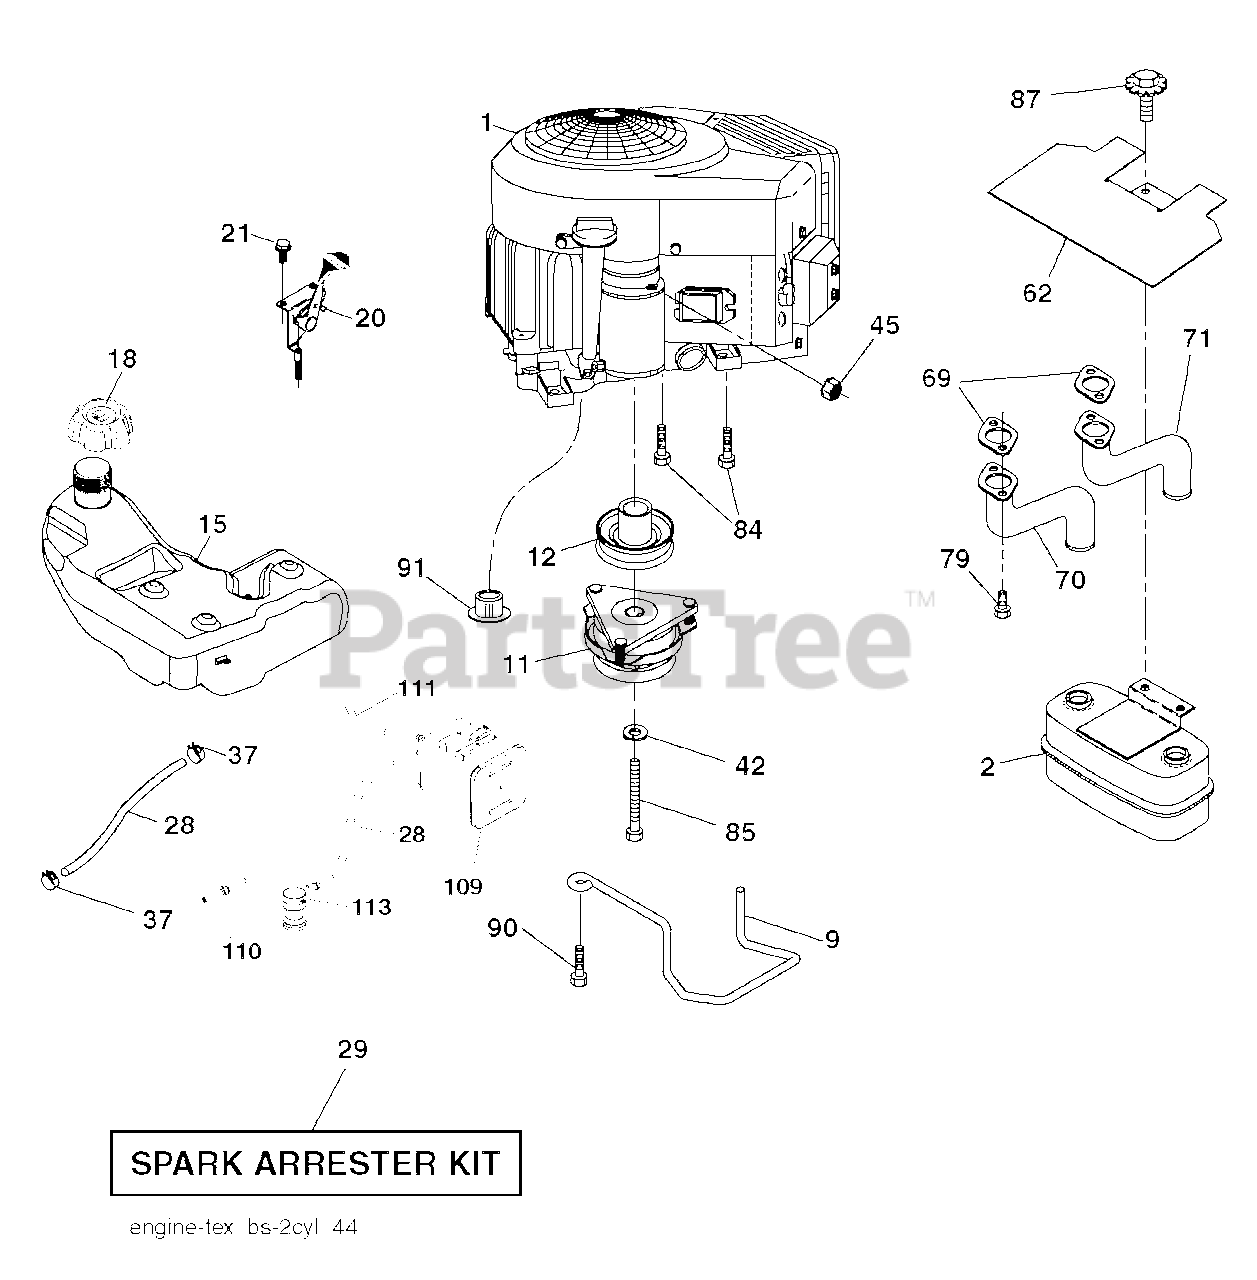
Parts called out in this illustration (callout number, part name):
2	MUFFLER.TWIN.CYL.LOW.TONE
9	KEEPER.BELT.ENGINE.4.2
11	CLUTCH.ELECTRIC.LT.48"*
12	PULLEY.ENGINE.TUFFTORQ
15	TANK.ASM.FUEL.3GA.CARB
18	CAP.ASM.FL.RITCH.3"E10.SYM.498
20	CONTROL.TH/CK.COBRA.B&S.TWN.
21	SCREW.#10 X 0.750.BOS
28	LINE.FUEL.64"REAR.EMIS
29	KIT.SPARK ARRESTOR 794945 B&S
37	HOSE CLAMP
42	LOCKWASHER
45	NUT
62	SHIELD.HEAT.MUFFLER
69	GASKET.MUFFLER
70	RP.EXHAUST.TUBE.LH.BS/TWIN
71	EXHAUST.TUBE.RH.BS/TWIN
79	SCREW.SOCKET.HEAD.5/16-18
84	SCREW.3/8-16
85	BOLT HEX 7/16-20X4-1/4"
87	Bolt, 5/16-18 X 1-3/4
90	SCREW 3/8-16X1
91	BUSHING.1.375OD
109	CANNISTER, CARBON
110	VALVE.ASM.ANTI-SLOSH
111	RP PURGE LINE
113	VALVE.SLANT.CARTRDG.90 DEG.TEX
